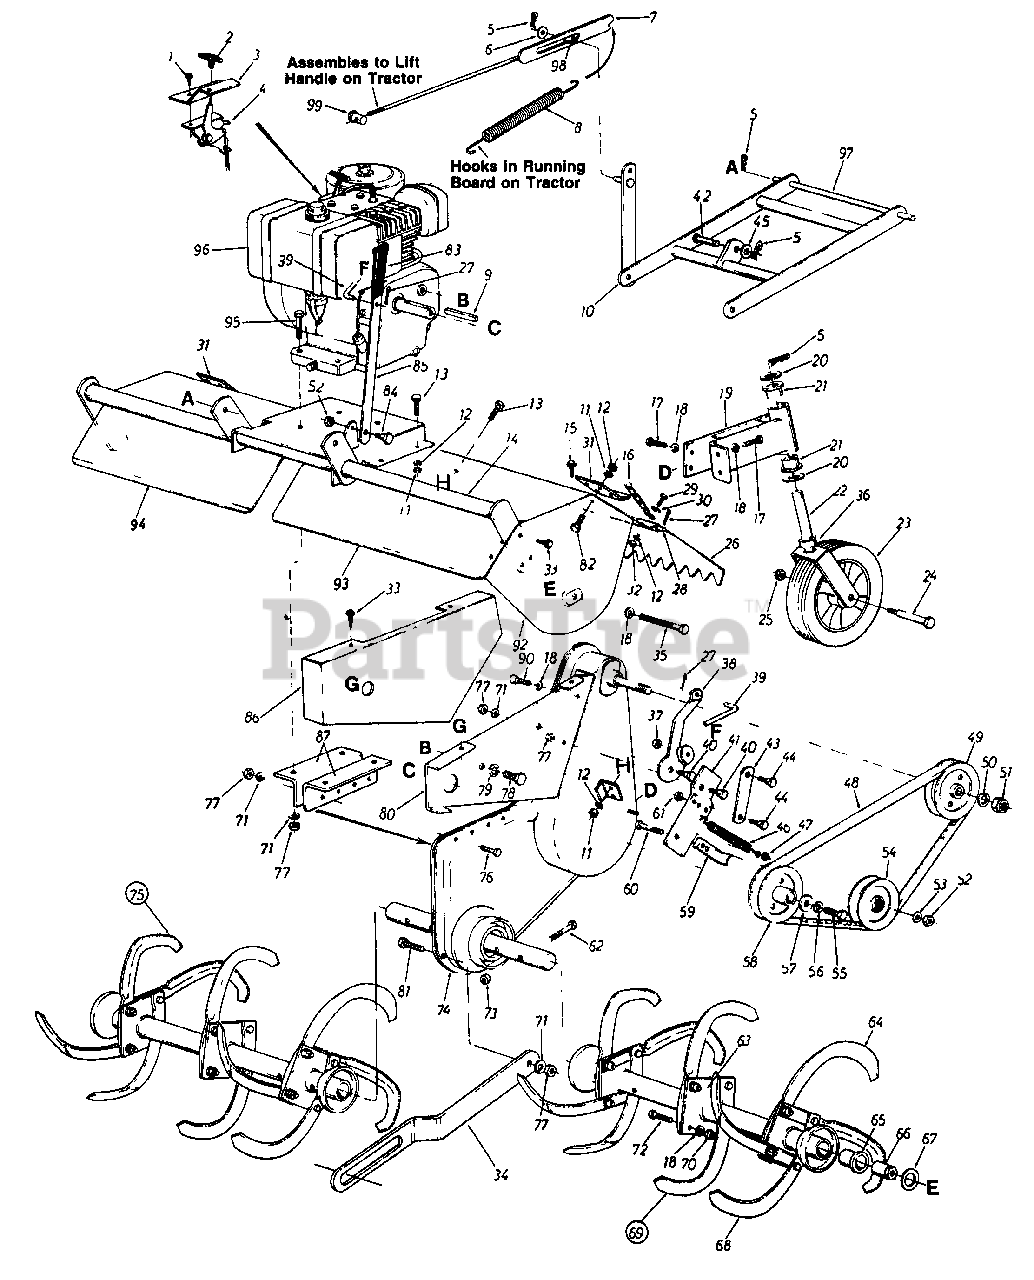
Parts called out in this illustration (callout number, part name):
1	Hex Wash. Hd. Self-Tap Scr. #8 x .50" Lg.
2	Throttle Control Knob
3	Throttle Control Bracket
4	Throttle Control Ass'y. Comp.
5	Internal Cotter Pin
6	Fl-Wash. 1/2" I.D. x .93" O.D.
9	Sq. Key 1/4" x 1/4" x 2.00" Lg.
12	L-Wash 1/4" I D
13	Hex Bolt 1/4-28 X 62" Lg.*
16	#2 Dog Chain x 20" Lg.
17	Hex Wash. Hd. Self-Tap Scr. 3/8-24 x .75" Lg.
18	L-Wash. 3/8" I.D.*
19	Swivel Wheel Support
20	Fl-Wash. 3/4" I.D. x 1.50" O.D.
21	Flange Bearing 3/4" I.D. x 1.00" O.D.
22	Swivel Wheel Caster
23	Wheel Assembly 10.0 x 2.75
24	Shoulder Bolt .623" I.D. x 3.62" Lg.
25	Hex Cent. L-Nut 7/16-14 Thd.
28	L.H. Flap Rod
28	R.H. Flap Rod
29	Hex Bolt 1/4-20 x .62" Lg.*
30	Fl-Wash. 1/4" I.D.
33	Hex Wash. Hd. Self-Tap Scr. 1/4" x .62" Lg.
34	Stabilizer Link
35	He Bolt 3/8-16 x 1.25" Lg.*
36	Spacer .752" I.D. x 1.25" O.D.
37	Hex Cent. L-Nut 5/16-18 Thd.
40	Shoulder Bolt 7/16" Dia. x 1.75" Lg.
45	Fl-Wash. .50" I.D. x 1.0" O.D. x .06
46	Extension Spring .62" O.D. x 6.12" Lg.
47	Hex Crown Nut 3/8-24 Thd.
48	V-Belt 1/2" x 43" Lg. (Kevlar)
49	1/2" "V"-Pulley 4.75" O.D. x .625" Bore
50	L-Wash. 5/8" I.D.
51	Hex Ins. L-Nut 5/8-18 Thd.
52	Hex Cent. L-Nut 3/8-16 Thd.
53	Fl-Wash. 3/8" I.D.
54	Idler Pulley 4.0" O.D.
55	Hex Bolt
56	L-Wash. 7/16" I.D.*
57	Fl-Wash. 7/16" I.D. x 1.38"
58	1/2" "V"-Pulley .475" O.D. x 1.00" Bore
61	Hex Cent. L-Nut 5/16-18 Thd.
62	Hex Bolt 7/16-14 x 2.00" Lg.
65	Flange Bearing 1.00" I.D.
66	Spacer
67	Thrust Wash. 1/2" I.D. x 1.55"
68	Tine-R.H.
69	Tine Assembly Comp.-L.H.
70	Hex Nut 3/8-24 Thd.
71	L-Wash. 5/16" I.D.
72	Hex Bolt 3/8-24 x 1.5" Lg.
73	Hex Cent. L-Nut 7/16-14 Thd.
77	Hex Nut 5/16-18 Thd.
78	Hex Bolt 1/2-20 x .88" Lg. (Grade 5)
79	L-Wash. 1/2" I.D.*
80	Clutch Support Bracket
81	Shld. Bolt .435 Dia. x .265 5/16-18 Thd.
82	Hex Bolt 1/4-28 x .75" Lg.
83	Plastic Grip
84	Shoulder Bolt .498 Dia. x .212 Lg.
87	Engine Mounting Bracket
90	Hex Bolt 3/8-16 x .62" Lg.
92	L.H.-Side Plate
96	8 H.P. Engine
97	Hitch Rod
98	Push Bar Sleeve .503" I.D. x .624" O.D.
99	Ferrule
